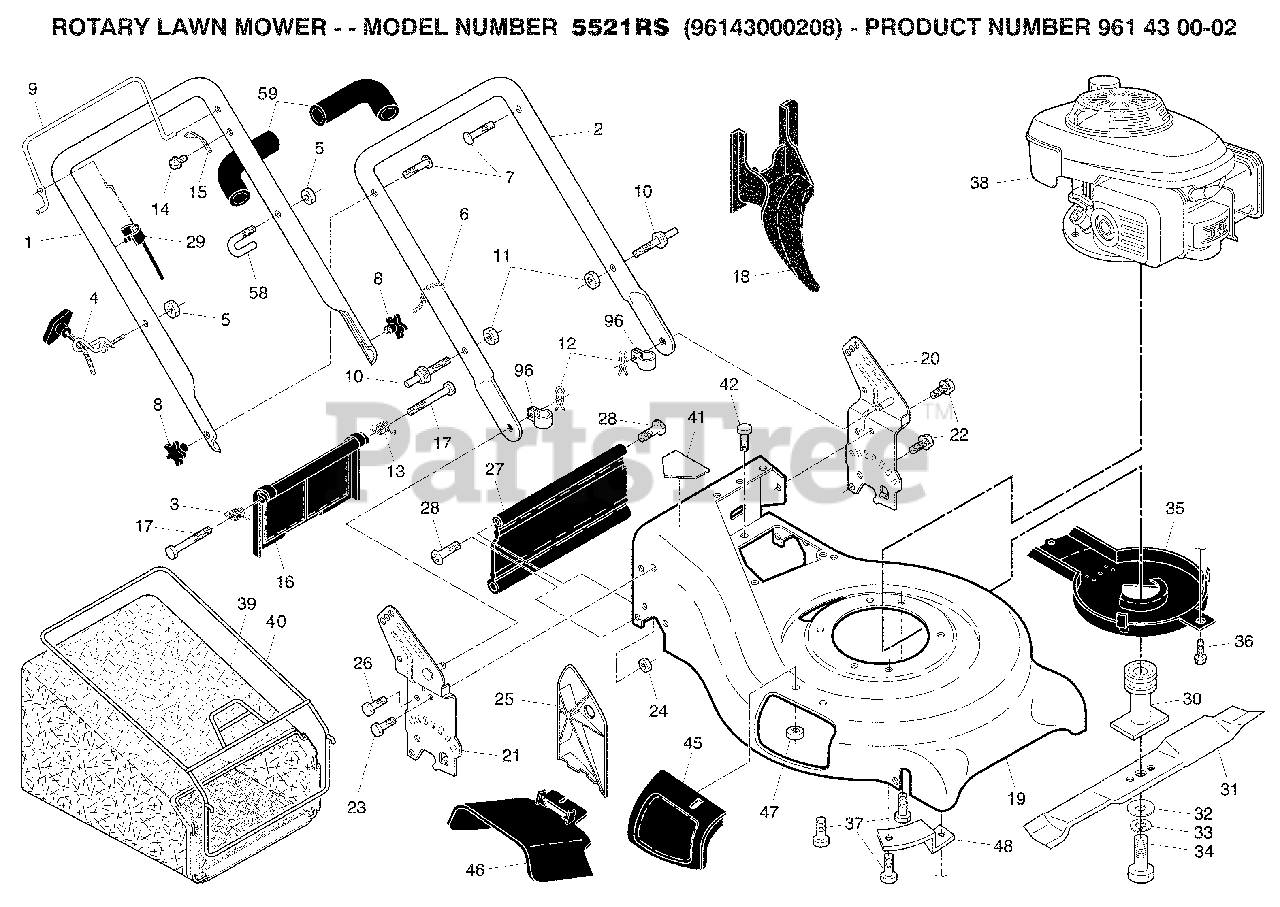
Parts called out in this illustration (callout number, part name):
1	Handle, Upper
2	Handle, Lower
3	Spring, Rear Door, RH
4	Guide, Rope, Side
5	Nut, Hex Lockwasher Insert 1/4-20
6	Wire, Tie
7	Bolt, Handle 5/16-18 x 1.75
8	Knob, Handle
9	Bail, Flat, Auto-Walk, Orange
10	Bolt, Carriage
11	Nut, Hex, Centerlock 5/16-18 UNC
12	Cotter, Hairpin
13	Spring, Rear Door, LH
15	Bracket, Upstop
16	Rear Door Assembly
17	Bolt, Rear Door
18	Plug, Mulcher
19	Kit, Housing
20	Handle Bracket Assembly, LH
21	Handle Bracket Assembly, RH
22	Screw, Hex Washer Head
23	Bolt, Hex Head 5/16-18 x 5/8
24	Nut, Hex, with Lock Washer Insert 5/16-18
25	Baffle, Side
26	Screw 12 x 5/8
27	Skirt, Rear
28	Screw, Hinge 1/4-20 x 1.25
29	Engine Zone Control Cable
30	Blade Adapter / Pulley
31	Blade, 21"
32	Washer, Hardened
33	Lockwasher, Helical Spring 3/8
34	Screw, Hex Head 3/8-24 x 1.38
35	Debris Shield
37	Bolt, Engine
39	Grassbag
40	Frame, Grassbag
41	Danger Decal
45	Mulcher Door Assembly
46	Deflector, Discharge
48	Mounting Bracket, Debris Shield
59	Grip, Handle, Foam, Smooth
96	Clip, Cable
